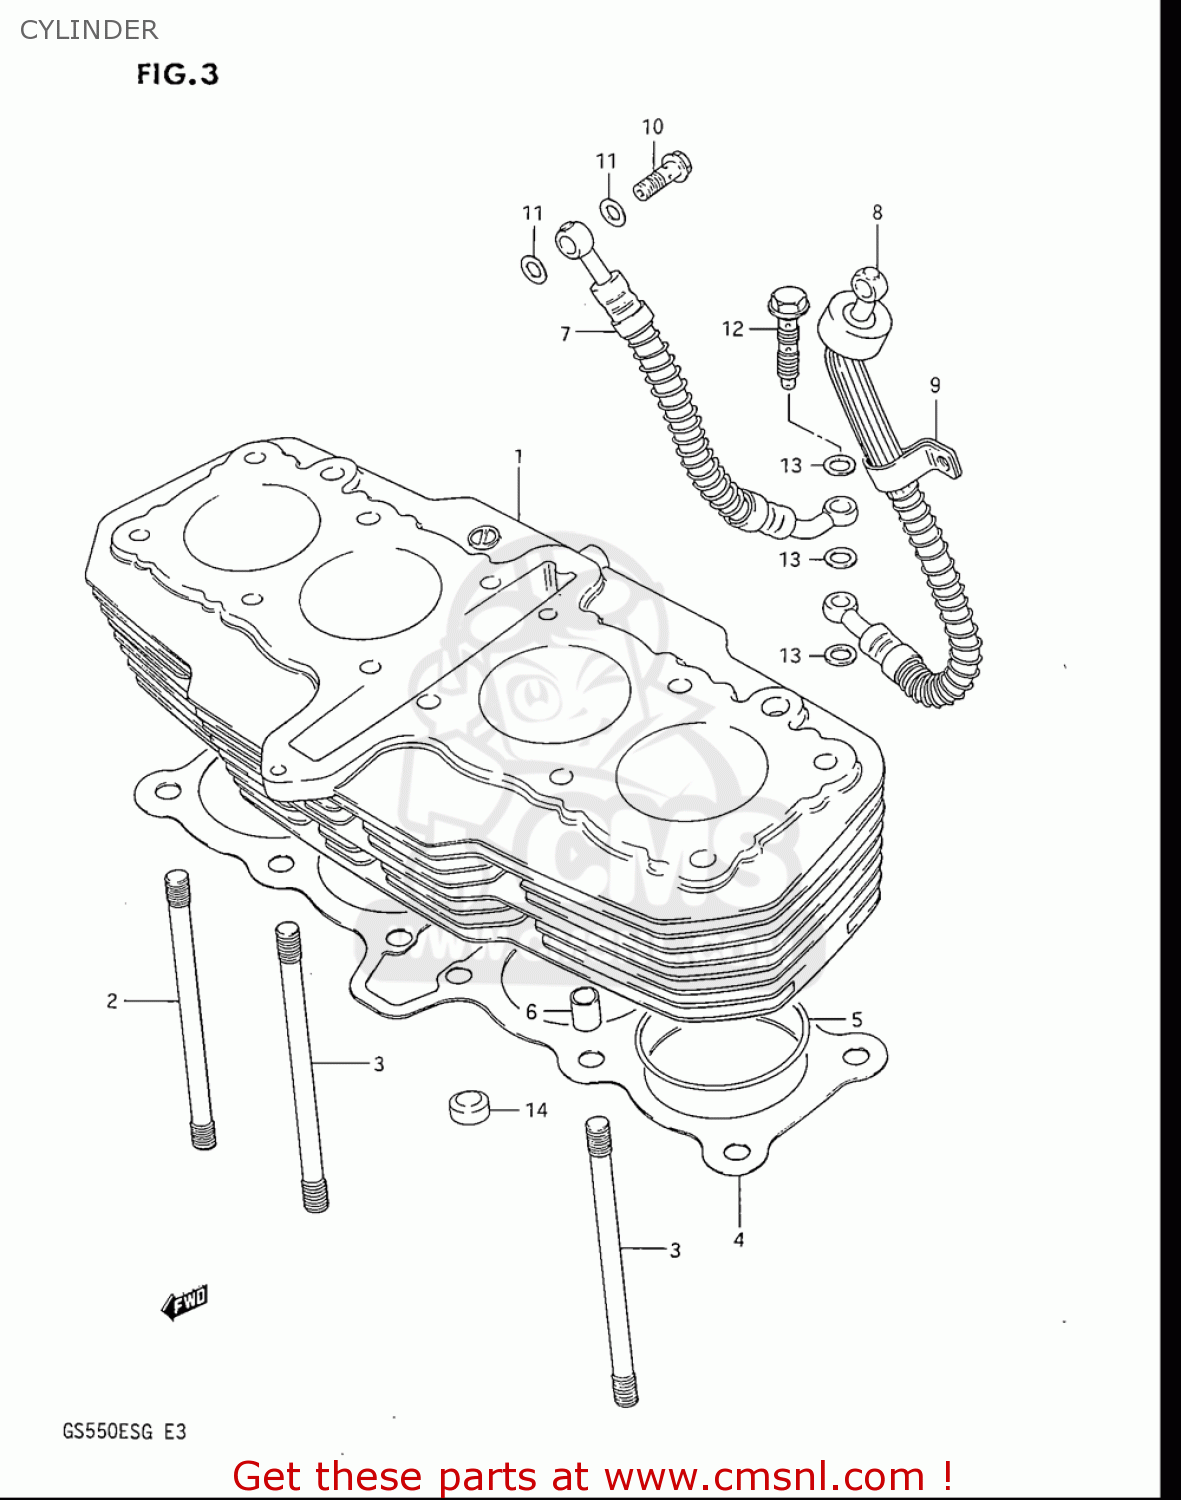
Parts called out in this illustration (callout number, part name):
2	BOLT,STUD
3	BOLT,STUD
4	GASKET,CYLINDER (NAS)
5	O RING(D:2,ID:61)
6	PIN
7	HOSE,OIL CRANKCASE,R
8	HOSE,OIL CRANKCASE,L
9	CLAMP,OIL HOSE CRANKCASE
10	BOLT UNION
11	GASKET(8.2X14X1) (NAS)
12	BOLT,OIL PIPE
13	WASHER(10X15X1.5)
14	PAD,CYLINDER HEAD
